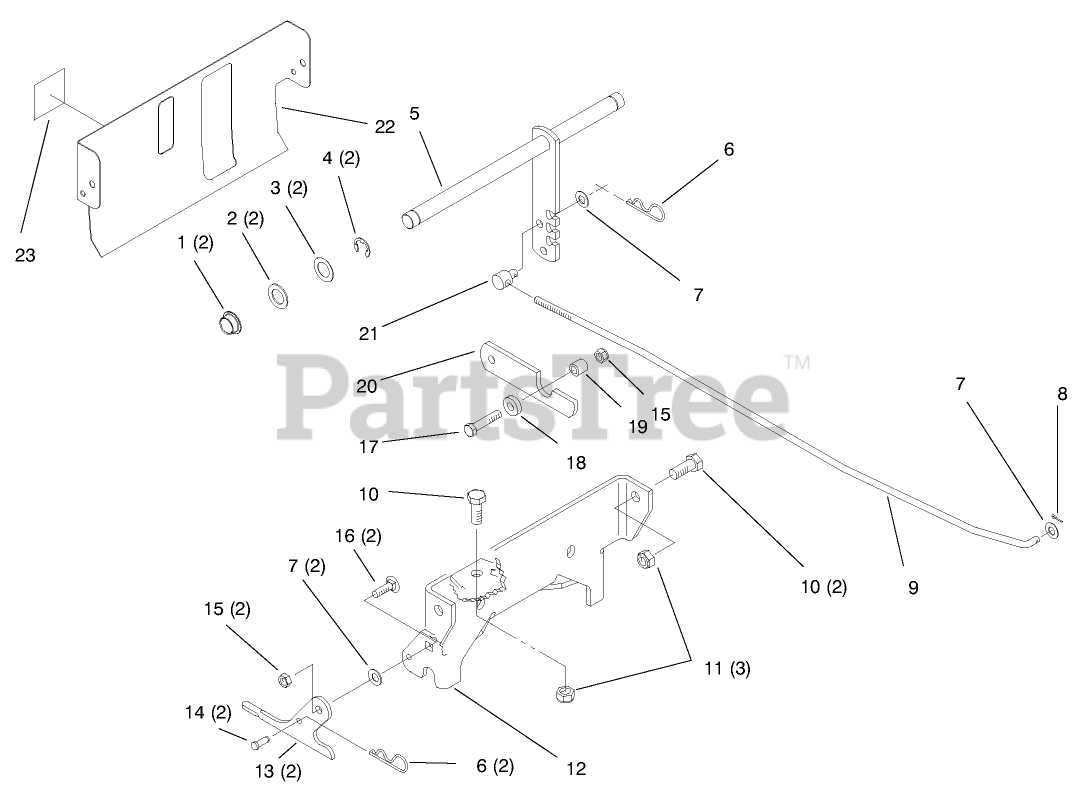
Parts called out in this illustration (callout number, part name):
1	BUSHING-BRONZE
2	WASHER
3	WASHER-SHIM
4	E-RING
5	LEVER ASM
6	PIN-HAIR
7	WASHER-FLAT
8	PIN-COTTER
9	ROD-LIFT
10	SCREW-HH
11	NUT-LOCK, NI
12	BRACKET-MOUNTING
13	PLATE-LATCHING
14	PIN-CLEVIS
15	NUT-LOCK, NI
16	BOLT-CARR
17	SCREW-HH
19	SPACER
20	CATCH-SPRING
21	TRUNNION-CLUTCH ROD
22	COVER-REAR
23	DECAL-LEVEL, FUEL
